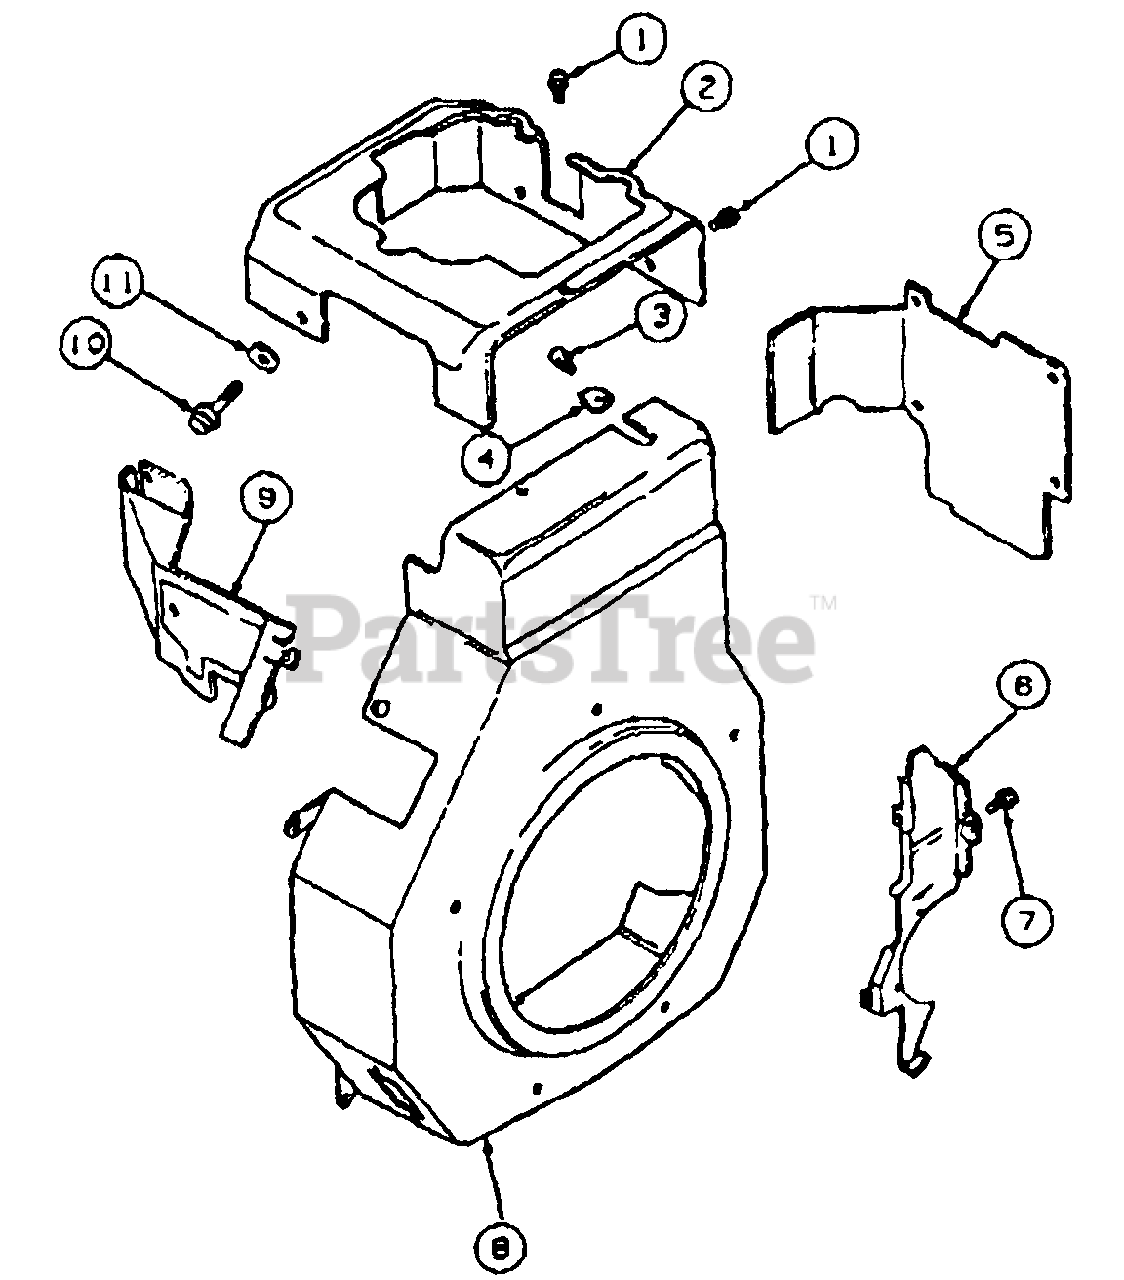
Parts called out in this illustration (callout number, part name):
1	Screw, Hex Flange, M5 x .8 x 10
2	Baffle, Cylinder Head
3	Screw, Hex Flange, M5 x 0.8 x 16
4	Clip, Mounting
5	Baffle, Cylinder
6	Plate, Blower Housing
7	Screw, Hex Flange, M5 x .8 x 20
8	Housing, Blower
9	Baffle, Intake Side
10	Screw, Hex Head
11	Washer, Plain
